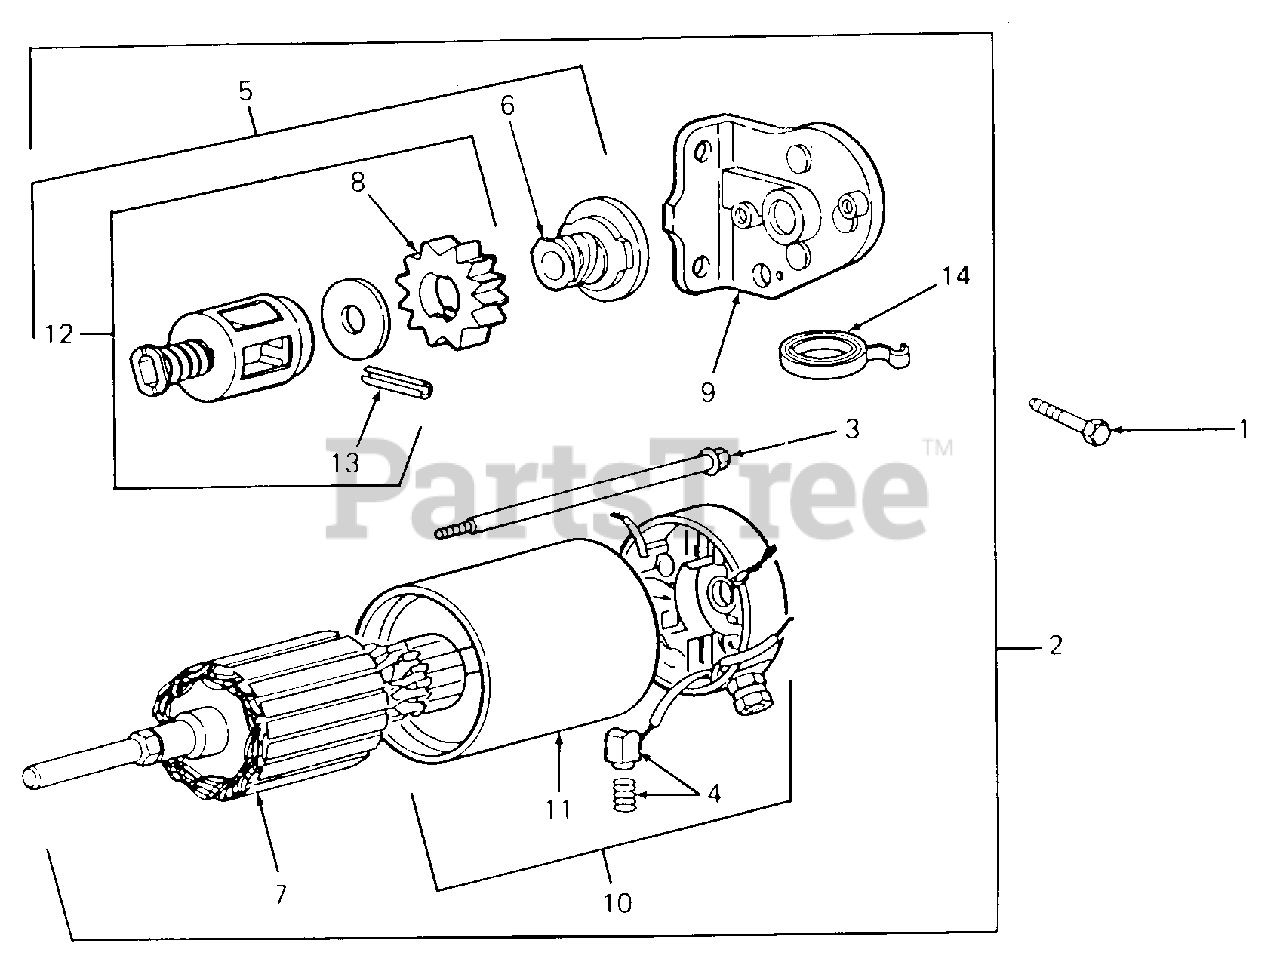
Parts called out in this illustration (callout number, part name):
1	Screw, Mounting
2	Motor, Starting
4	Brush Assy
5	Kit, Bendix Drive
6	Drive, Starter
7	Armature Assy
8	Gear
10	Cap Assy, Commutator End
11	Housing Assy
12	Kit, Spring
13	Pin, Roll
14	Brush, Spring Set
